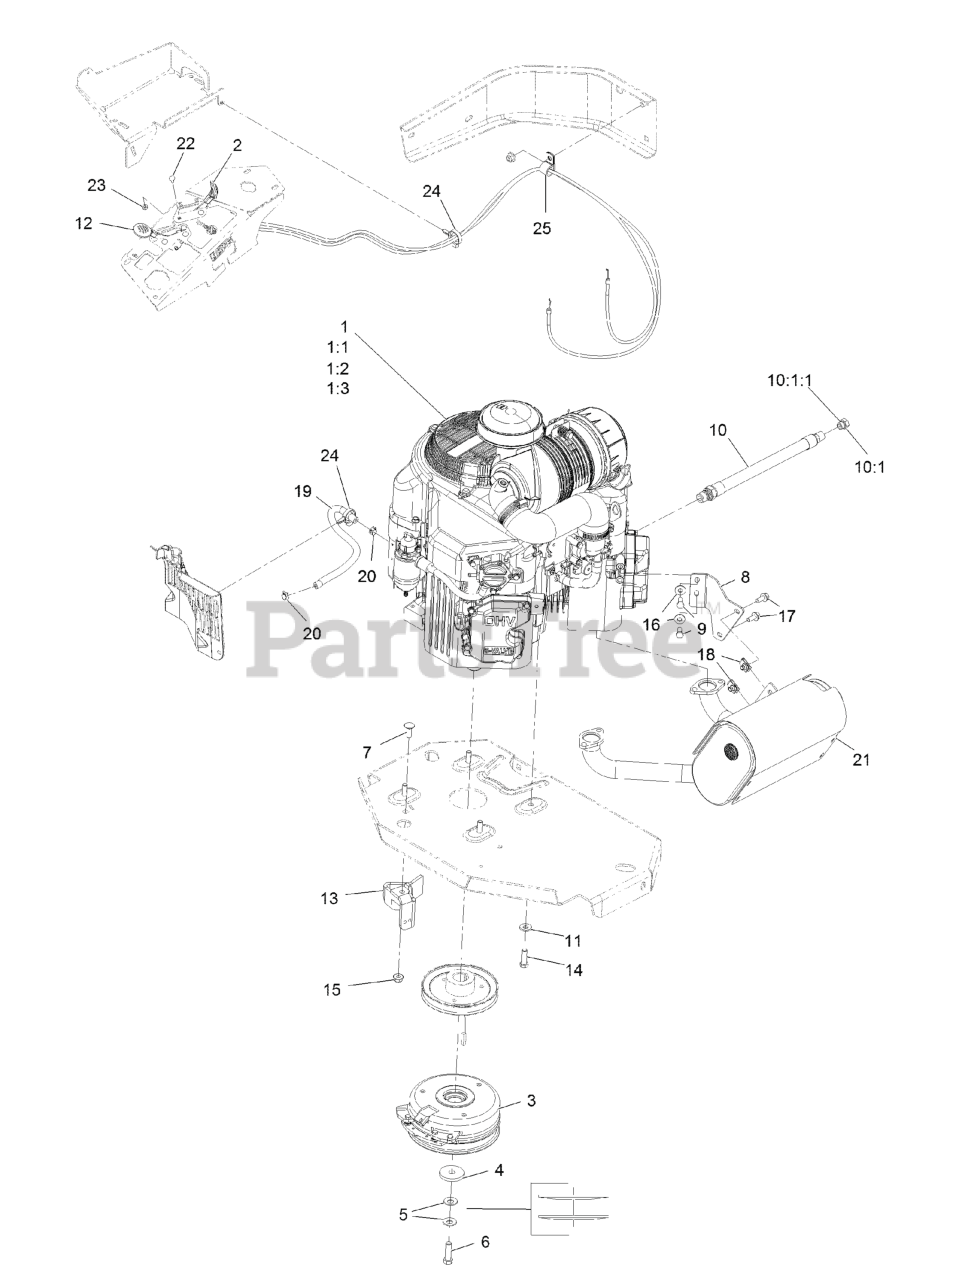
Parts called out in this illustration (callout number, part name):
1:1	Kawasaki 49065-Engine Oil Filter
1:2	Kawasaki 11013-Engine Air Filter
1:3	Kawasaki 11013-7045 Safety Filter
2	CONTROL, CHOKE
3	CLUTCH KIT
4	WASHER-CLUTCH
5	WASHER-SPRING
6	SCREW-HH 7/16-20 X 1 1/2 W/LOCTITE
7	SCREW-CARR
8	BRACKET-MUFFLER
9	SCREW-HH
10	ENGINE OIL DRAIN HOSE ASM
10:1	PLUG-HH
10:1:1	O-RING
11	WASHER-BELLEVILLE
12	ASM,THROTTLE CABLE
13	CLUTCH-ANCHOR
14	SCREW-HH
15	NUT-HF, NI
16	WASHER-SPRING
17	SCREW-HHF
19	HOSE-FUEL
20	CLAMP-HOSE
21	MUFFLER
22	BOLT-CARR
23	NUT-LOCK, NI
24	CLAMP-HOSE
25	CLIP-LOOM
